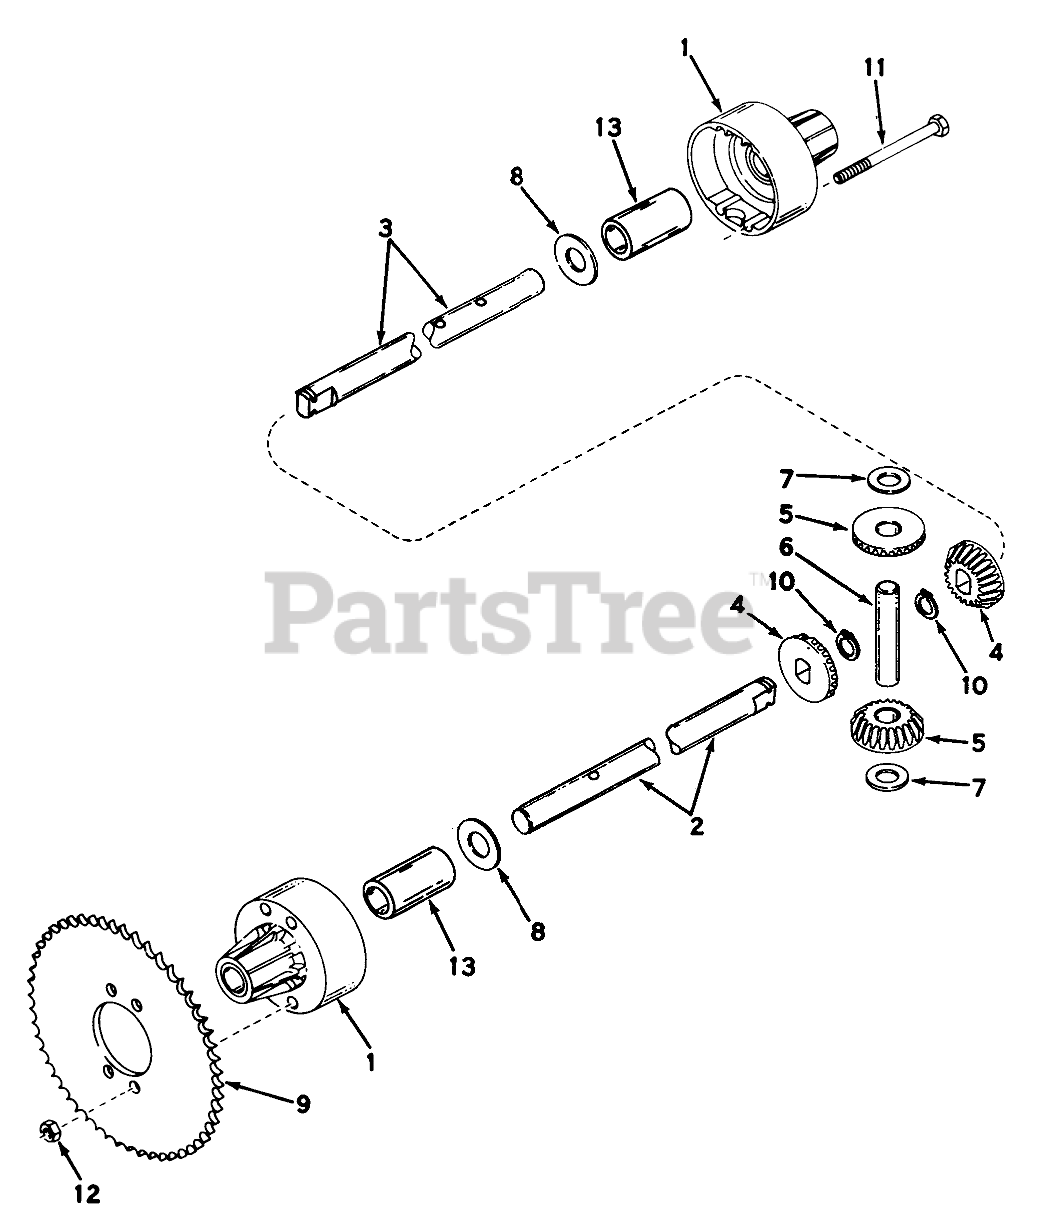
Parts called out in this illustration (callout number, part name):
1	Housing, Differential Carrier
2	Axle (8-59/64" long)
3	Axle (12-37/64" long)
4	Bevel Gear
5	Gear Pinion
6	Pin Drive
7	Washer, Thrust
8	Washer
9	Sprocket (40 teeth)
10	Snap Ring
11	Screw-Hex Hd.
12	Nut-Lock
13	Bushing
